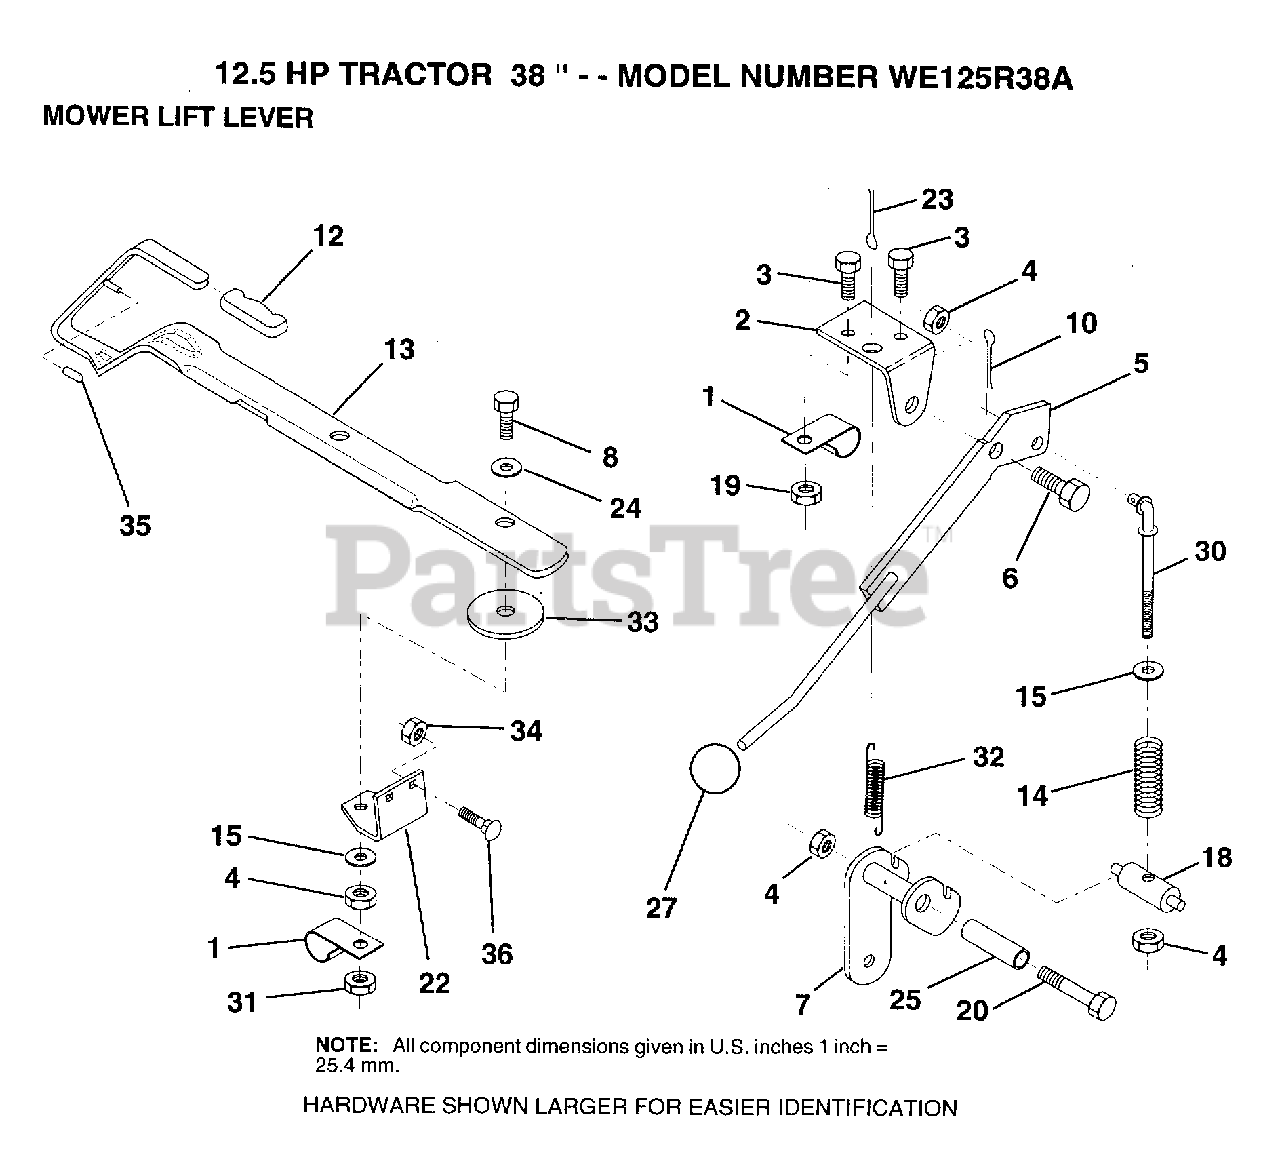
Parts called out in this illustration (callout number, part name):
1	"CLIP,INSULATOR"
2	BRKT CLUTCH
3	BOLT
5	CLUTCH LEVER AS
6	"BOLT, SHOULDER LT"
7	MWR CLUT ARM ASM
8	BOLT
10	COTTER PIN
12	GRIP HANDLE
13	LEVER LIFT LR
14	COMP CLUTCH SPRNG
15	WASHER HYT
18	TRUNNION
20	BOLT
22	LIFT LEVER BRKT
24	WASHER
25	TUBE SPACER
27	KNOB
30	ROD TENSION CLUTC
31	LOCKNUT
32	SPRING EXT
33	WASHER
35	VINYL CAP RED
36	BOLT
